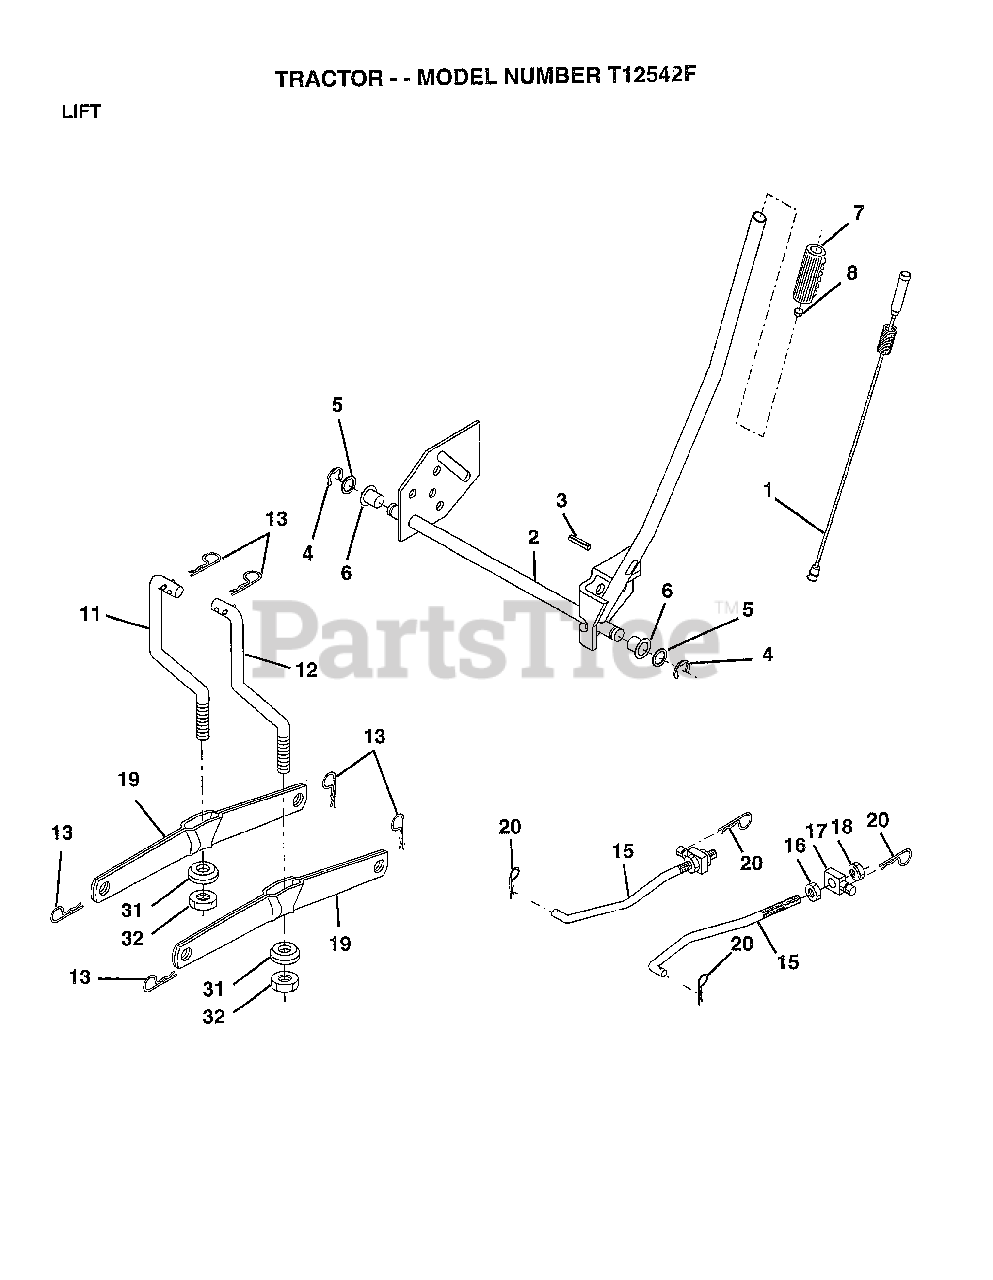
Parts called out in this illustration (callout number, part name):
1	WIRE ASM W.SPRING
2	"SHAFT ASM LIFT,RH"
3	PIN-GROOVE LT
5	WASHER
6	NYLON BEARING
7	GRIP
15	LINK.FRONT
16	NUT
17	TRUNION
18	NUT.LK.W/WSH.1/2.
19	ARM SUSP REAR
20	RETAINER SPRING
31	BEARING PVT LH
32	NUT.CROWNLOCK.3/8
